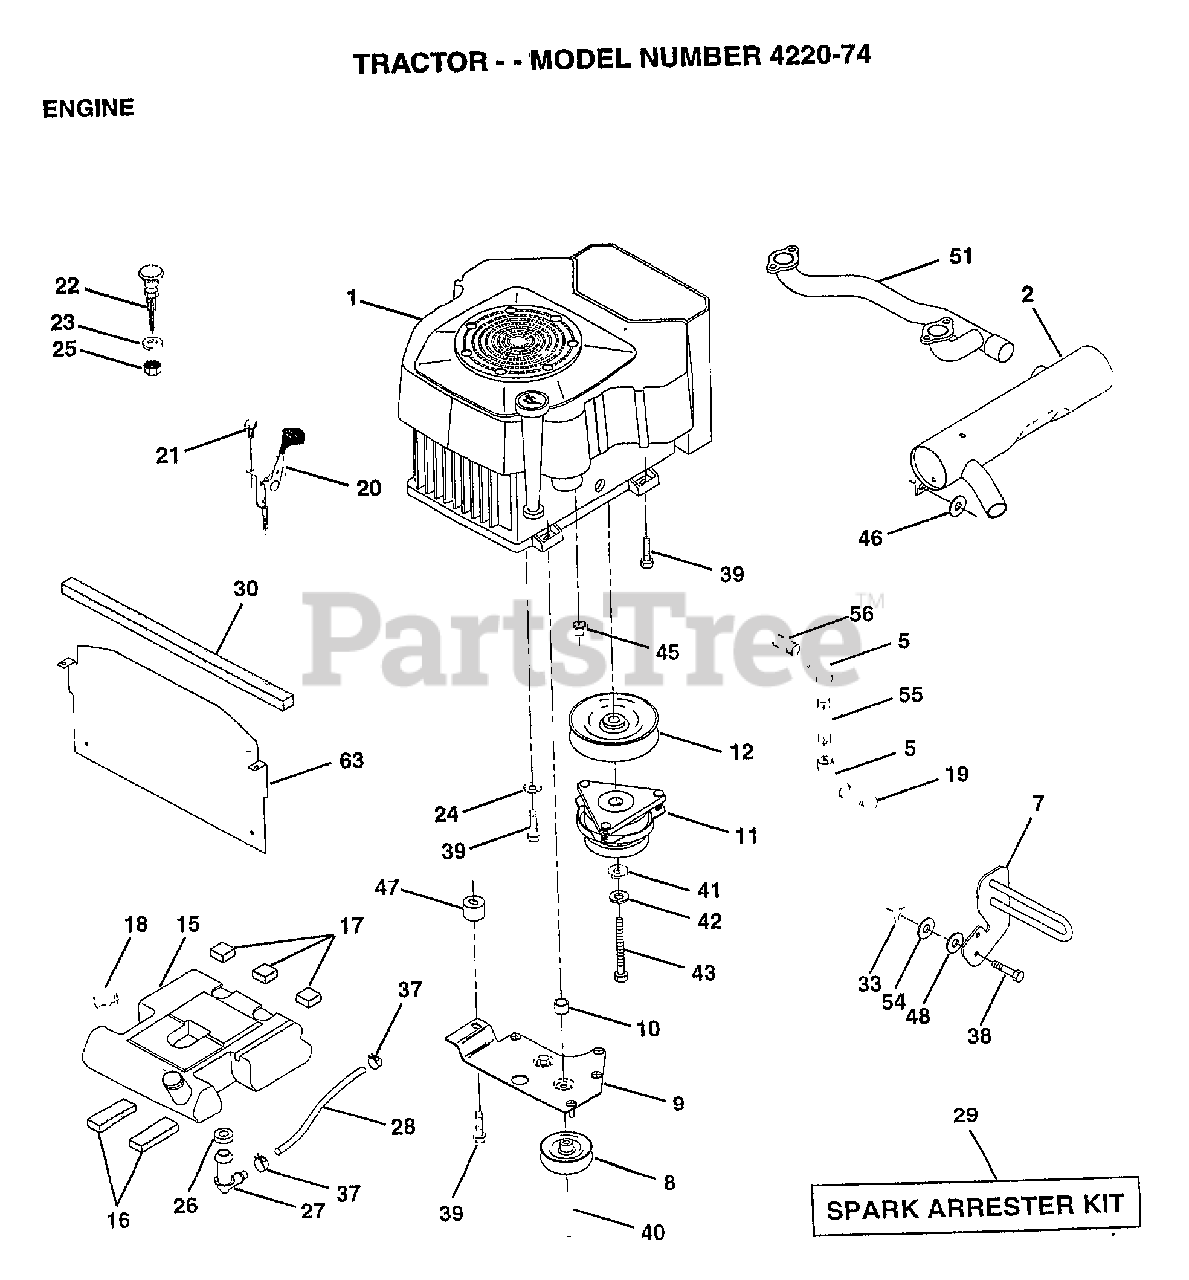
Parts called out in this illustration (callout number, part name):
1	ENGINE, KOHLER
2	MUFFLER ASM.
5	ELBOW
7	GUARD.MUFFLER.ASM
9	KEEPER ASM BELT
10	BUSHING.
12	PULLEY.ENG.CLUTCH
15	TANK FUEL REAR
16	PAD IDLER TI
17	PAD-SPACER LT
18	CAP ASM FUEL
19	PLUG T
21	SCREW LT
22	CHOKE CONTROL
23	WASHER
24	LOCKWASHER
25	"NUT,KEPS 3/8-24IM"
26	BUSHING OUTLET T
27	STEM.TANK.FUEL
29	SPARK ARREST KIT
30	FOAM-STRIP LT
33	NUT
37	HOSE CLAMP
38	"BOLT,HEX"
39	SCREW.3/8-16X2.25
40	SCREW.TT.3/8-16X4
41	WASHER
42	LOCKWASHER
43	BOLT.7/16-20X4.25
45	NUT
46	WASHER HYT
47	SPACER.ENGINE
48	WASHER T
51	PIPE CROSSOVER
54	WASHER
56	NIPPLE.PIPE
63	HEAT.SHIELD.VGT.
